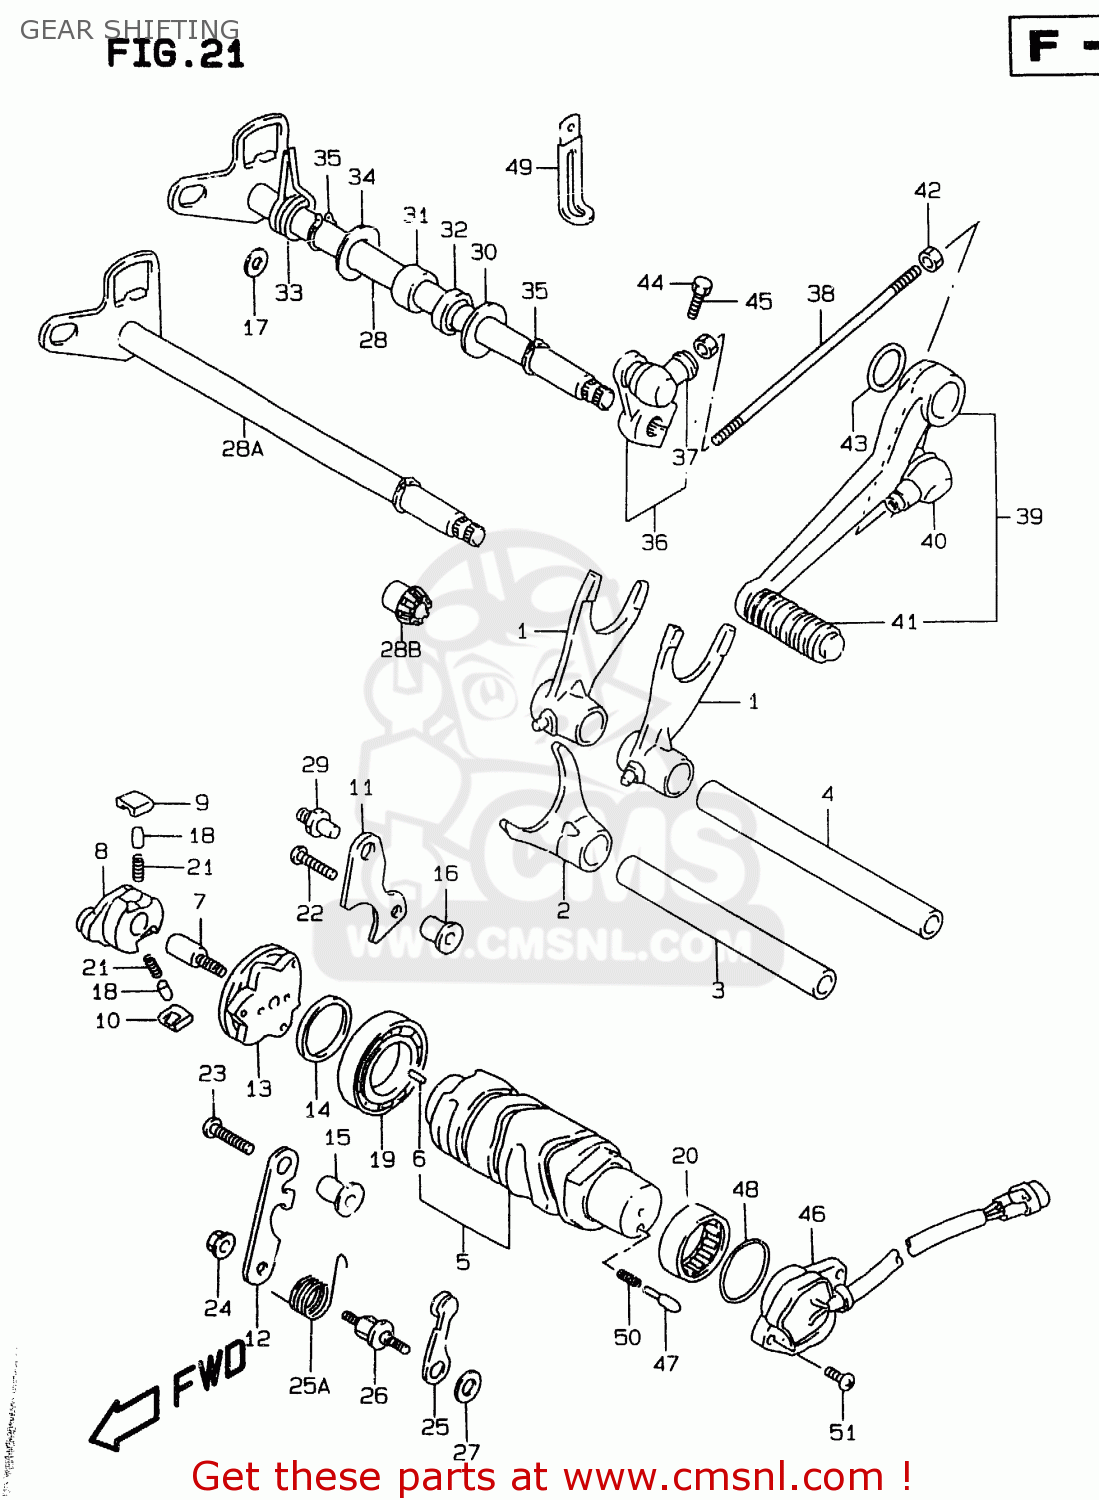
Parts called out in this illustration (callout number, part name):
1	FORK,GEAR SHIFT NO.1
2	FORK,GEAR SHIFT NO.3
3	SHAFT,GEAR SHIFT FORK
4	SHAFT,GEAR SHIFT FORK(L:128)
5	CAM,GEAR SHIFT
6	PIN
7	PIN,SHIFT CAM DRIVEN GEAR
8	SHIFTER,GEAR SHIFT CAM
9	PAWL,GEAR SHIFT NO.1
10	PAWL,GEAR SHIFT NO.2
11	LIFTER,GEAR SHIFT PAWL
12	GUIDE,GEAR SHIFT CAM
13	PLATE,GEAR SHIFT CAM
14	WASHER(25X32X3)
15	SPACER(6.1X10X16)
16	SPACER(6.1X10X16)
17	SPACER(7X10X5)
18	PIN, SHIFT PAWL CLICK
19	BEARING(25X47X8)
20	BEARING(25X32X12)
21	SPRING
22	SCREW 6X30
23	SCREW
24	NUT
25	STOPPER,GEAR SHIFT CAM
25A	SPRING,SHIFT CAM STOPPER
26	SUPPORT,CAM STOPPER ARM
27	WASHER
28	SHAFT COMP,GEAR SHIFTING
28A	SHAFT,GEAR SHIFT
28B	BUSH,GEAR SHIFT SHAFT
29	STOPPER,GEAR SHIFT CAM
30	WASHER(14X29X0.8)
31	BEARING(14X20X12)
32	SEAL,OIL(14X22X6)
33	SPRING
34	WASHER
35	CIRCLIP
36	ARM,GEAR SHIFT LINK
37	COVER,DUST
38	ROD,GEAR SHIFT LINK(L:165)
39	LEVER ASSY,GEAR SHIFT
40	COVER,DUST
41	RUBBER,GEAR SHIFT PEDAL
42	NUT
43	WASHER(18X24X1)
44	BOLT
45	NUT
46	BASE ASSEMBLY,GEAR SHIFT TERMINAL
47	PIN(5X15.5)
48	O RING(D:2.4,ID:25.7)
49	CLAMP(L:45)
50	SPRING
51	SCREW
